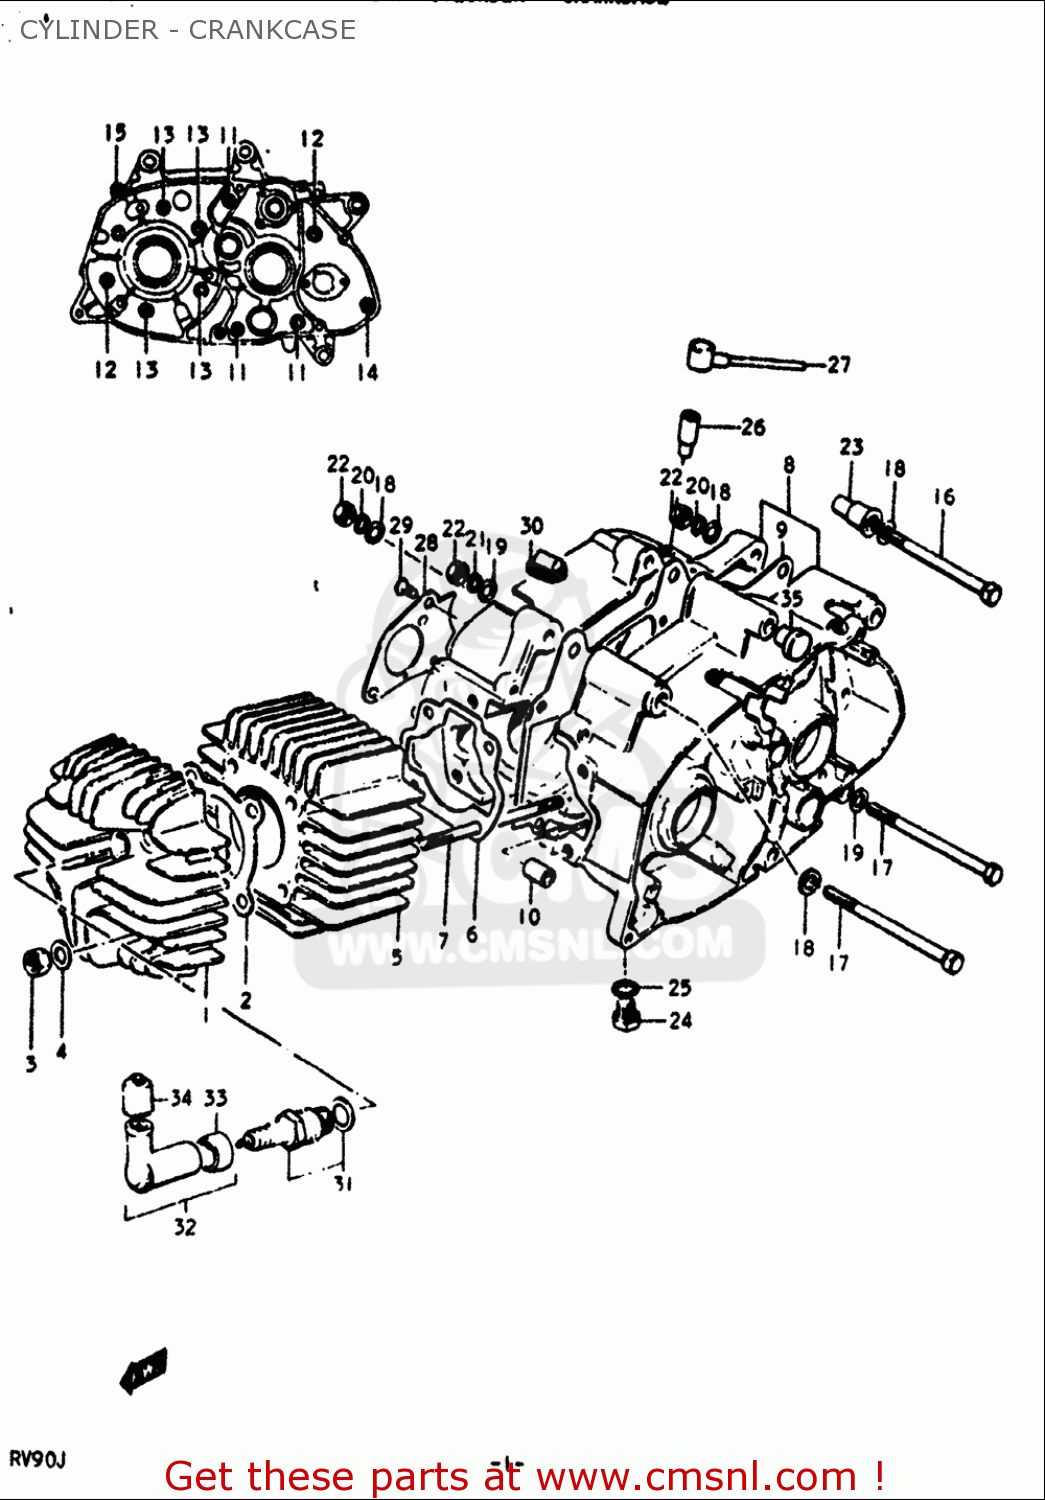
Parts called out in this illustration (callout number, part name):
1	HEAD,CYLINDER
2	GASKET,CYLINDER HEAD (NAS)
3	NUT
4	WASHER
5	CYLINDER
6	GASKET,CYLINDER (NAS)
7	BOLT,STUD
9	GASKET,CRANKCASE (NAS)
10	PIN
11	SCREW
12	SCREW
13	SCREW
14	SCREW
15	SCREW
16	BOLT 8X100
17	BOLT(8X115)
18	WASHER
19	WASHER
20	WASHER,LOCK
21	WASHER,LOCK
22	NUT
24	PLUG(MAGNETO)
25	GASKET(14X19.2X2) (NAS)
26	PLUG,T/M BREATHER
27	GASKET (NAS)
28	PLATE,OIL RESERVOIR
29	SCREW
30	GROMMET
31	SPARK PLUG
32	CAP,SPARK PLUG
34	SEAL,HIGH TENSION CORD
